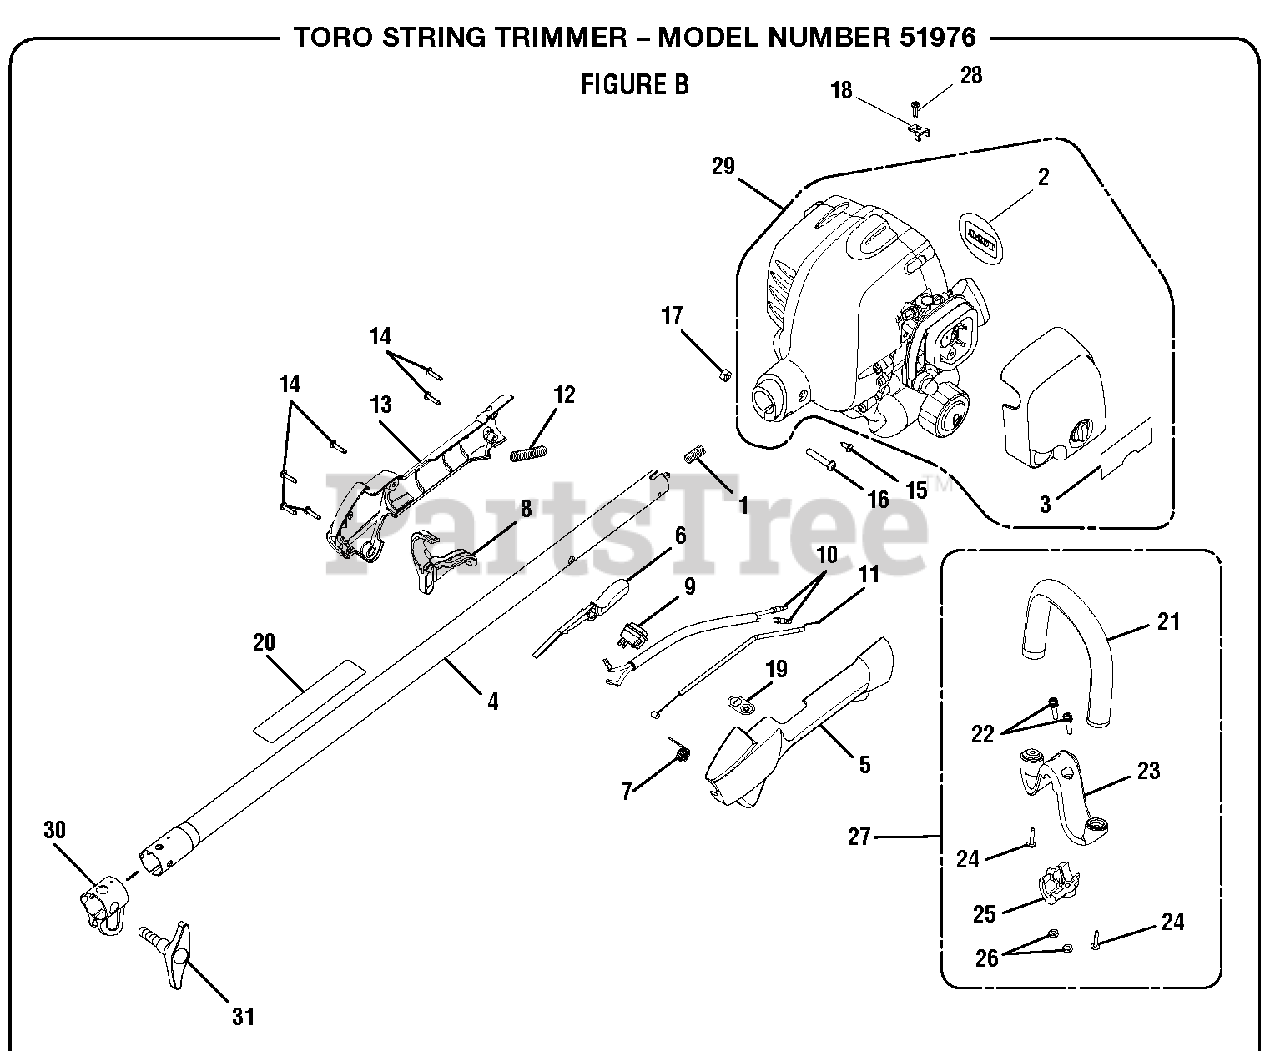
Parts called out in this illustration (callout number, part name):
1	Compression Spring
2	Logo plate
3	Lower Start Label
4	Upper Shaft Assembly
5	Rear Handle Support
6	Lock-off Button
7	Trigger Spring
8	Trigger
9	On/Stop Switch
11	Cable, Throttle
12	Corrugated Tube
13	Rear Handle Cover
14	Screw (M4 x 16 mm)
15	Screw (#8-16 x 1/2 in. Tri-Lobular)
16	Screw (M6 x 1-30 mm)
17	Hex Nut (M6.3 x 1)
18	Throttle Cable Clamp
19	On/Stop Label
20	Warning Label
21	Front Handle w/Grip
22	Slotted Torx (#12-24 x 1 in.)
24	Screw (10-14 x 1 in.)
25	Clamp
26	Hex Nut (12-24)
27	Front Handle Assembly
28	Screw (M4 x 16 mm)
29	Powerhead Assembly
30	Boom Clamp
